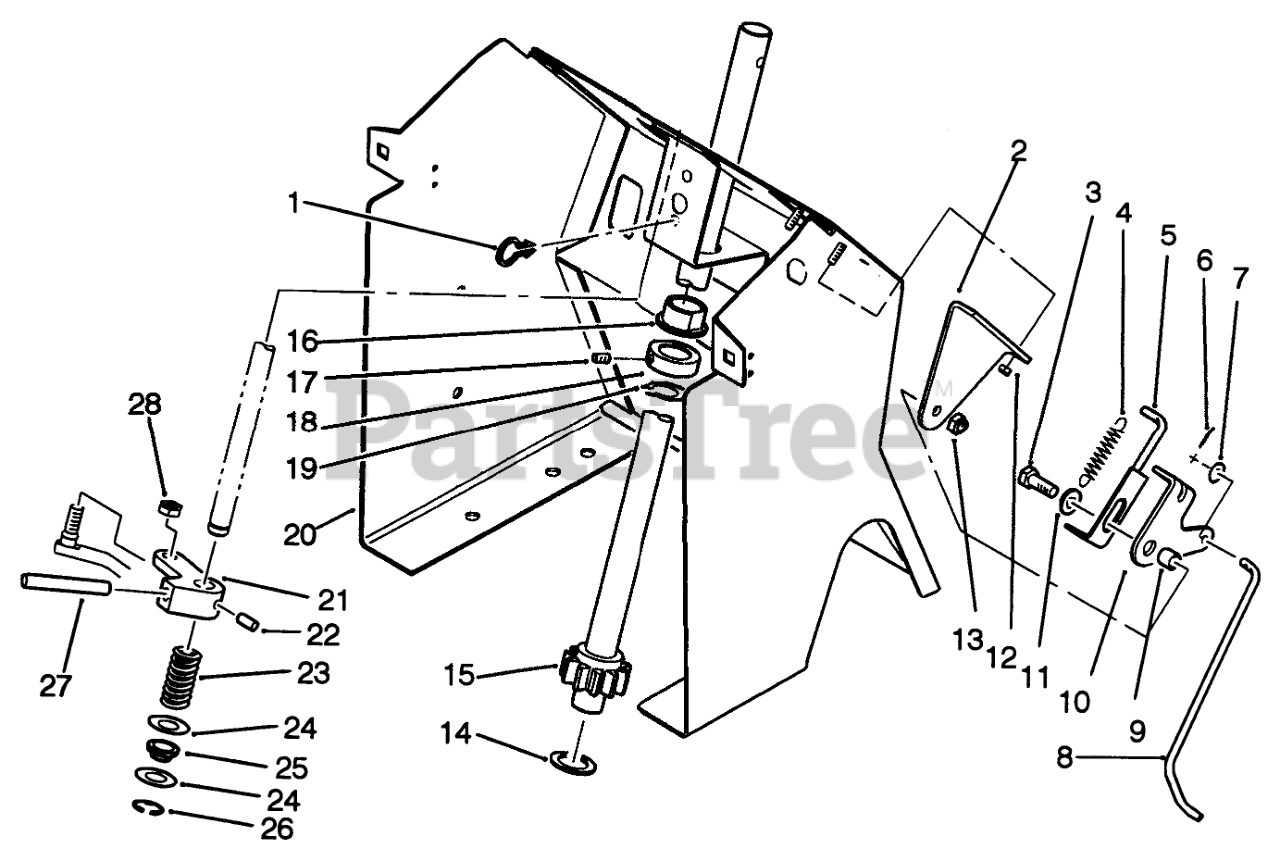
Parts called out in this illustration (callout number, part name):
1	CLIP-SNAP IN
2	SUPPORT-INDICATOR B
3	Bolt
4	SPRING-EXTENSION
5	WLDMT-INDICATOR R
6	Cotter Pin
7	WASHER-PLAIN
8	ROD-INDICATOR
9	SPACER
10	RETAINER-INDICATO B
11	WASHER-FLAT
12	Nut
13	NUT-LOCK, NI
14	WASHER
15	WLDMT-STRG SHAFT
16	COLLAR
17	SCREW-HSH
18	BEARING-FLANGED
19	RING-RETAINING
20	WLDMT-HOODSTAND B
21	ARM-SPEED CONTROL
22	PIN-SPIROL
23	SPRING-COMPRESSION
24	SHIM-WASHER
25	BUSHING-NYLINER
26	RING-SHAFT, EXT
27	PIN-SPIROL 5/16X2.25
28	NUT-LOCK
